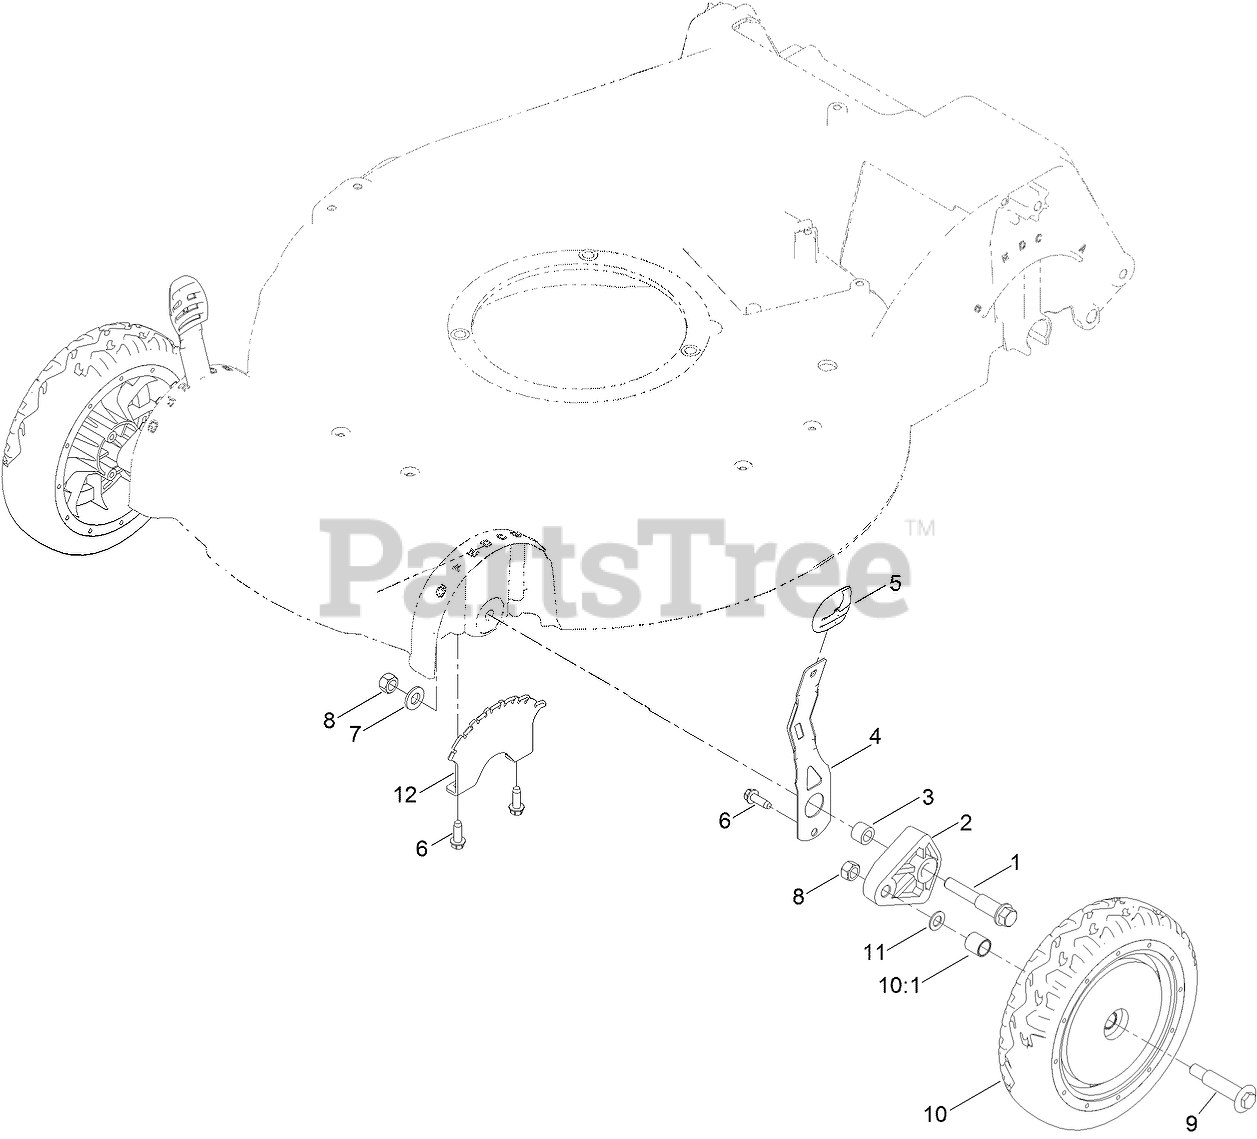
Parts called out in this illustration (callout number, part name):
1	SCREW-SHOULDER
2	ARM-PIVOT
3	SPACER-WHEEL
4	ARM-SPRING
5	KNOB-LEVER, HOC
6	SCREW-HWHTF
7	WASHER-FLAT
8	LOCKNUT
9	BOLT-SHOULDER
10	8 INCH WHEEL ASM
10:1	BUSHING
11	WASHER
12	PLATE-HOC
